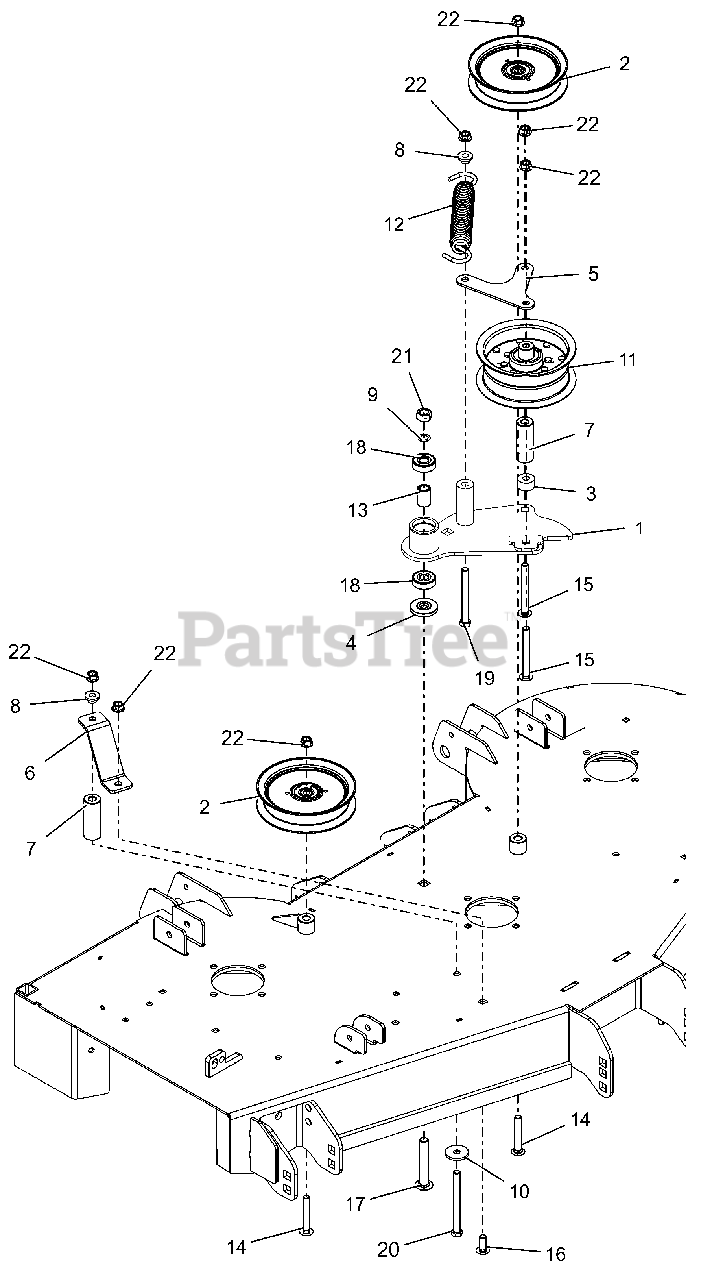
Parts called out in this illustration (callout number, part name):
1	WLDMT, IDLER ARM (BLACK)
2	IDLER, FLAT 5.00"
3	SPACER .390X1.000X.562
4	SPACER, IDLER ARM
5	BRKT, SUPPORT (BLACK)
6	BRKT, SPRG ANCHOR (BLACK)
7	SPCR, TUBE (BLACK)
8	BSHG-FLG .385X.500X.875X.406
9	WASHER, .500X.750X.020 THRUST
10	WSHR-FL-STL .406X1.375X.135 YZ
11	PULLEY, FLAT 5.00X2.36X.375
12	SPRING, EXTENSION
13	SPACER .510 X .75 X 1.1485
14	@BLT-RDHDSQNK .38-16X2.50 G5YZ
15	@BLT-RHDSSQNK .38-16X3.50 G5YZ
16	@BLT-RDHDSHSQNK.38-16X1.0 G5YZ
17	BLT,RDHDSQSHNK.50-13X3.25 G5YZ
18	BRG-BALL .500X1.38X.437
19	@BLT-HEX .38-16X3.75 GR5 YWZC
20	@BLT-HEX .38-16X4.25 GR5 YWZC
21	@NUT-LK-CTR .50-13 YWZC
22	NUT-LK-CTR-FLG .38-16 YWZC
